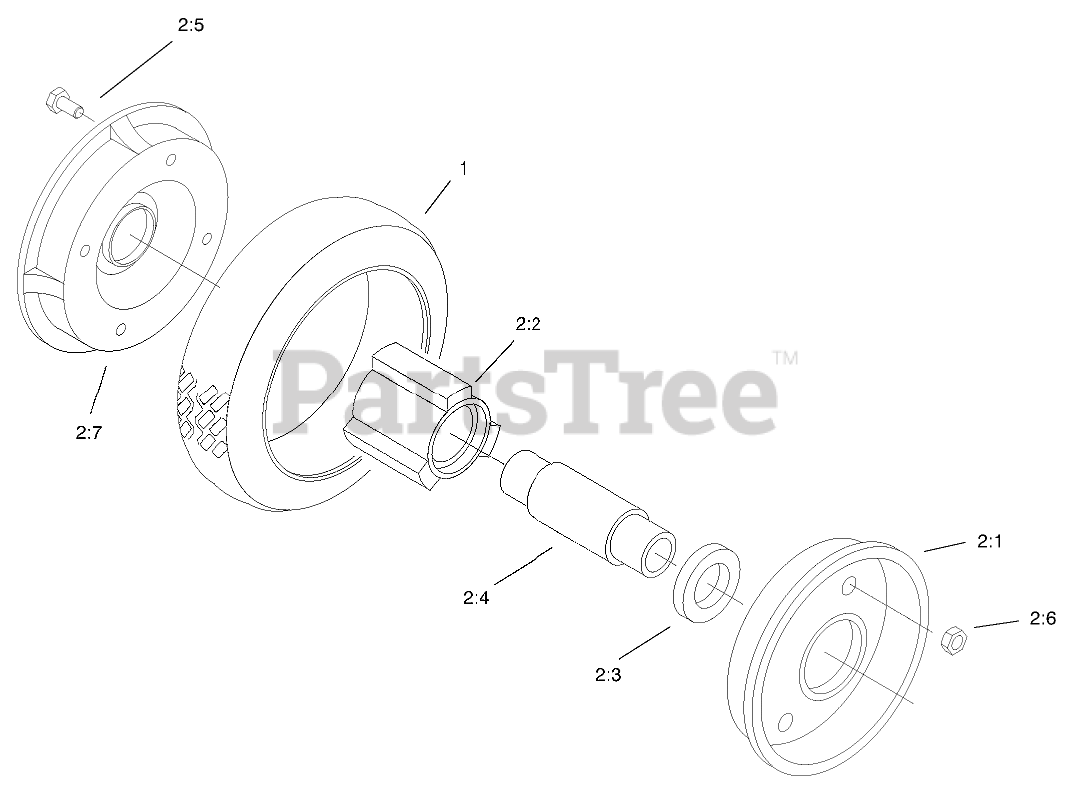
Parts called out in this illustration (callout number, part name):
2	ASM-Wheel and Tire
2:1	PLATE-WHEEL, HALF
2:2	HUB-BEARING
2:3	BEARING-WHEEL
2:4	SPACER-BEARING
2:5	SCREW-HH
2:6	NUT-LOCK, NI
2:7	WHEEL HALF AND GEAR ASM
